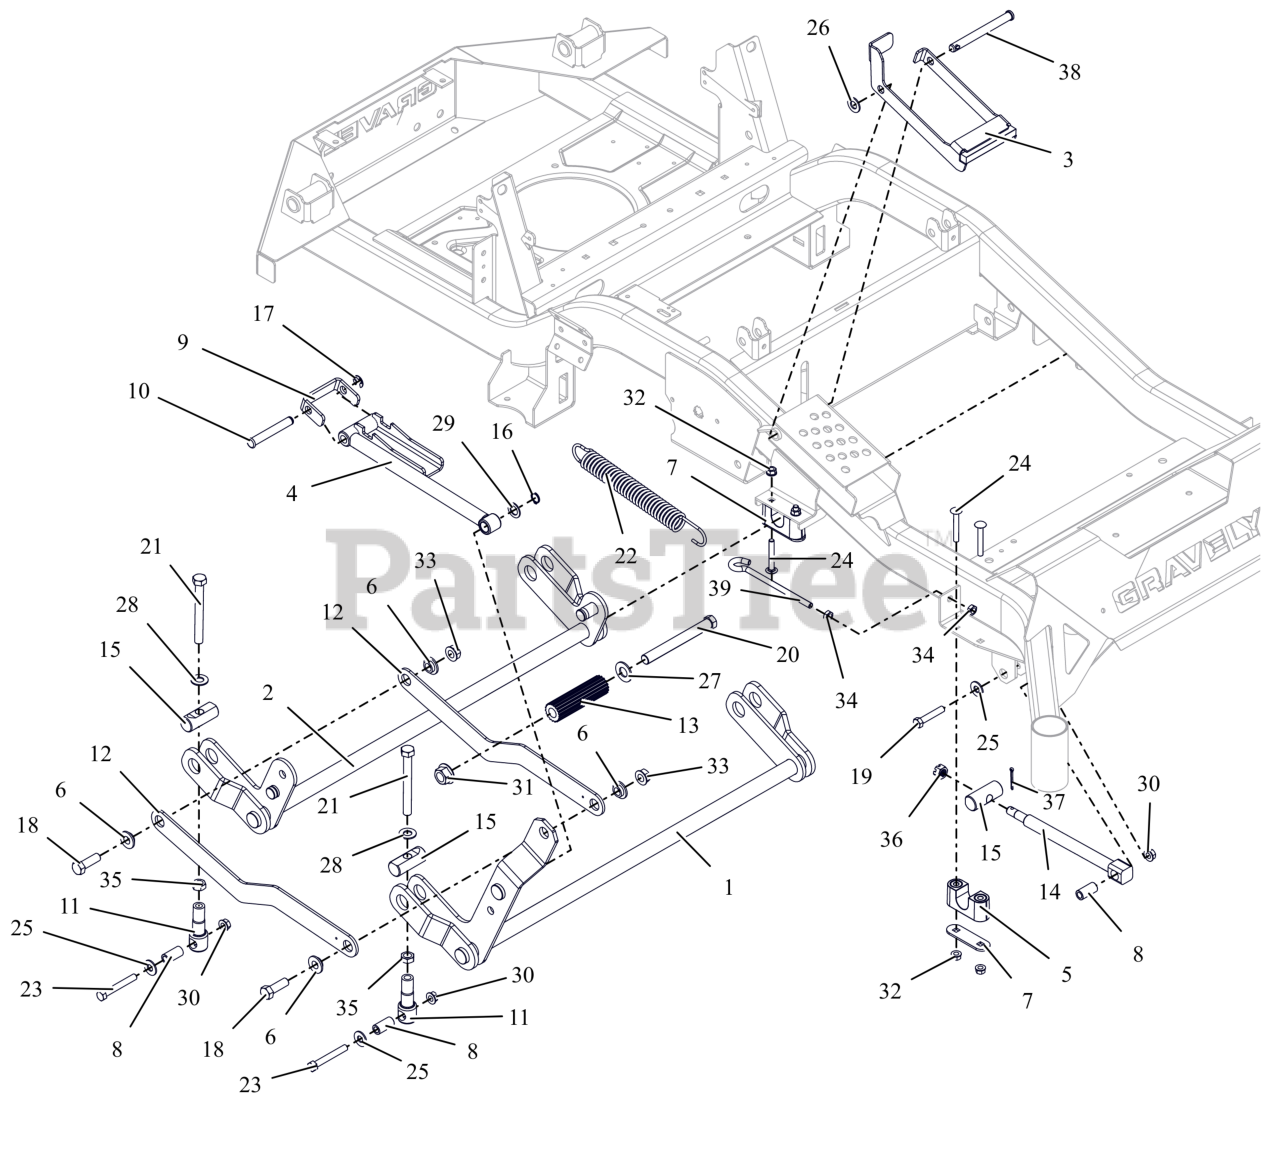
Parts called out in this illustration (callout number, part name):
1	WLDMT, FRONT DECK LIFT PIVOT
2	WLDMT, REAR DECK LIFT PIVOT
3	WLDMT, HOC TRANSFER LOCK (BLACK)
4	WLDMT, HOC LIFT ARM (BLACK)
5	ASM-BUSHING, DECK LIFT
6	BSHG-FLG .515X.750X.310X1.120
7	PLATE, BEARING SUPPORT
8	SPACER, DECK LEVELING
9	BRKT, HOC LINE
10	PIN, .499/.494 x 3.385 CLEVIS
11	LINK, DECK LIFT FORMED
12	LINK, DECK
13	ROD, FOOT PEDAL (BLACK)
14	DRAG,LINK-HD
15	PIN, DECK LIFT
16	RG-RTNG-EXT .625X.050
17	RG-RTNG-EXT .500X.042 (E)
18	BLT,HEX .50-13X1.50 G5 ZCC
19	BLT,HEX .38-16X2.00 G5 ZCC
20	BLT, HEX .62-11X5.50 G5 FBP
21	BLT, HEX .50-13X4.50F G8 ZCC
22	SG-TENS .162X1.25X8.25 WLD 25
23	BLT, HEX .38-16X2.75 G8 ZCC
24	BLT, RHSSN.31-18X2.25 G5 ZCC
25	WSHR,FLT .438X1.00X.083 ZCC
26	WSHR-FL-NYL .518X1.000X.080
27	WSHRFLT 5/8SAE CARBHARD FBP
28	WSHR, FLT .557X1.040X.102 ZCC
29	WSHR, FLT .630X1.005X.062 ZCC
30	NUT-LK-TOP-FLG .38-16 ZC120
31	NUT,FLG-TOP LK .625-11 FBP
32	NUT,LK-CTR-FLG .31-18 GF ZCC
33	NUT-LK-TOP-FLG .500-13 GF ZCC
34	NUT-JAM .375-16 G2 ZCC
35	NUT-JAM .500-13 G2 ZCC
36	NUT-SL .50-13
37	PIN,CTR.12X1.25EXTPRSQCT ZC120
38	PIN, SLIC-.500X4.97X4.55 -ZC
39	BOLT,.38-16 X 5.25-.62 DIA EYE
